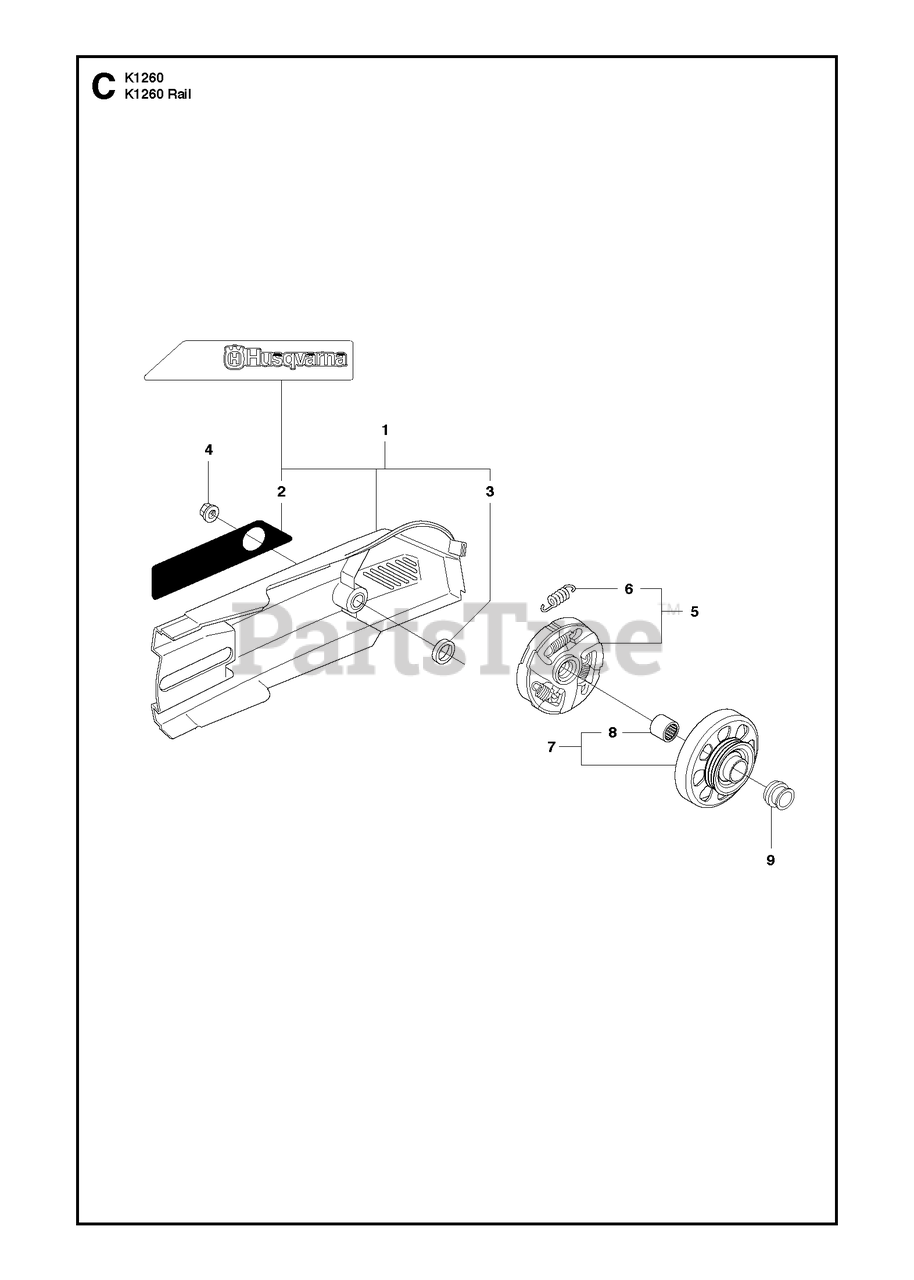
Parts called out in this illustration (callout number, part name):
1	BELT GUARDIncl. 2, 3
3	SPACING SLEEVE
5	CLUTCH ASSYIncl. 6
6	CLUTCH SPRING
7	DRIVE SPROCKET"14"". Incl. 8"
7	DRIVE SPROCKETRail, "16"". Incl. 8"
8	NEEDLE BEARING
9	SPACING SLEEVE
